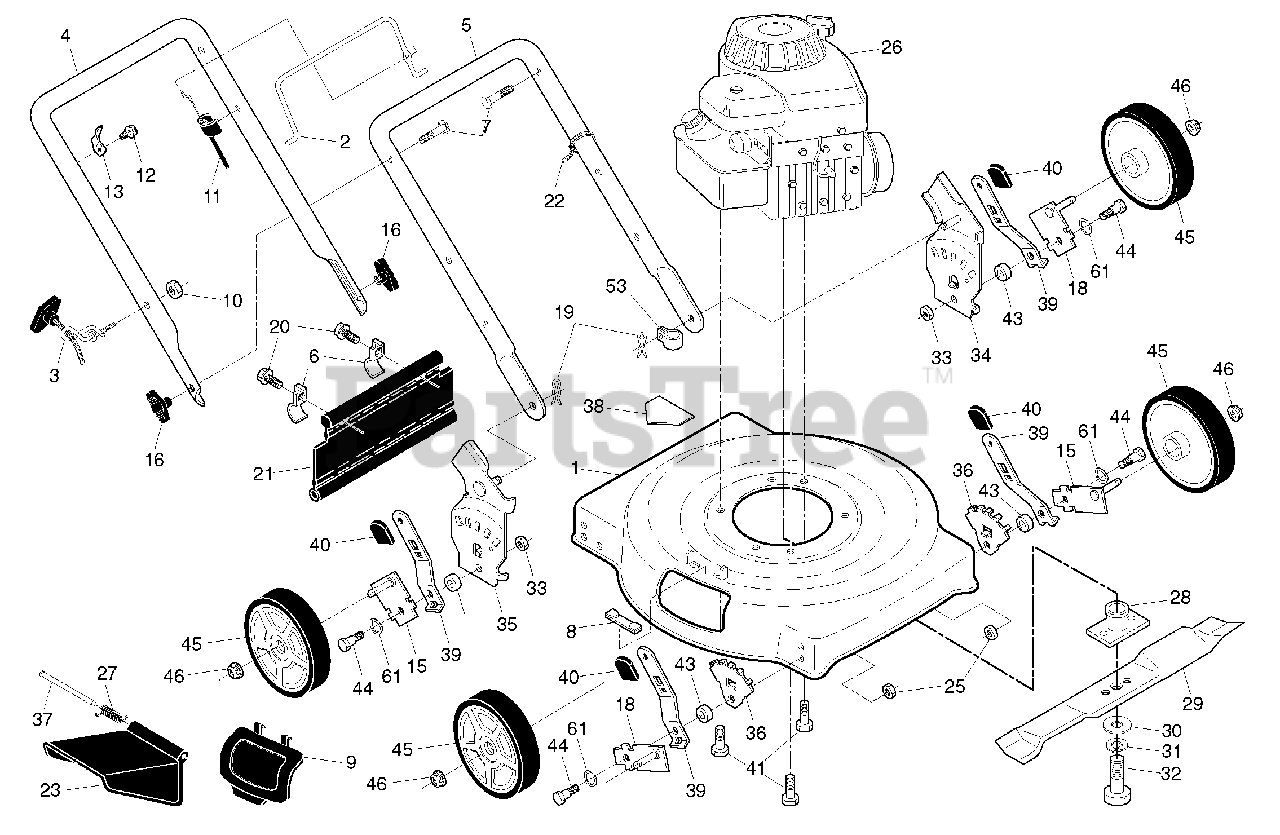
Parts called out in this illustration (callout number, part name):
1	Kit, Housing
2	Control Bar
3	Rope Guide
4	Upper Handle
5	Lower Handle
6	Shoulder Bolt 5/16-18 x 1/2
7	Handle Bolt 5/16-18
8	Clip, Closeout
10	Locknut, Hex 1/4-20
11	Engine Zone Control Cable
12	Screw, Hex Head, Threaded, Rolled #10-24 x 1/2
13	Up-Stop Bracket
15	Axle Arm Assembly, Left Front & Right Rear
16	Handle Knob
18	Axle Arm Assembly, Right Front & Left Rear
19	Hairpin Cotter
20	Screw, Tapping, Hex Washer Head #10-24
21	Rear Skirt
22	Wire Tie
23	Discharge Guard
25	Nut, Hex, Flangelock 5/16-18
27	Torsion Spring
28	Blade Adapter
29	22" Blade
30	Hardened Washer
31	Helical Lockwasher 3/8
32	Screw, Hex Head, Grade 8, 3/8-24 x 1-3/8
33	Nut, Hex, Flangelock 5/16-18
34	Wheel Bracket Support (Left)
35	Wheel Bracket Support (Right)
36	Wheel Bracket Adjuster
37	Hinge Rod
38	Danger Decal
39	Selector Spring
40	Selector Knob
41	Screw, Hex Head, Threaded, Rolled 3/8-16 x 1
43	Spacer
44	Shoulder Bolt 5/16-18 x .33
45	Wheel & Tire Assembly, Rear
46	Nut, Hex, Flangelock 3/8-16
47	Wheel & Tire Assembly, Front
53	Clip, Cable
61	Washer, Curved, Cylindrical
61	Operator's Manual, English
61	Operator's Manual, French
61	Repair Parts Manual
